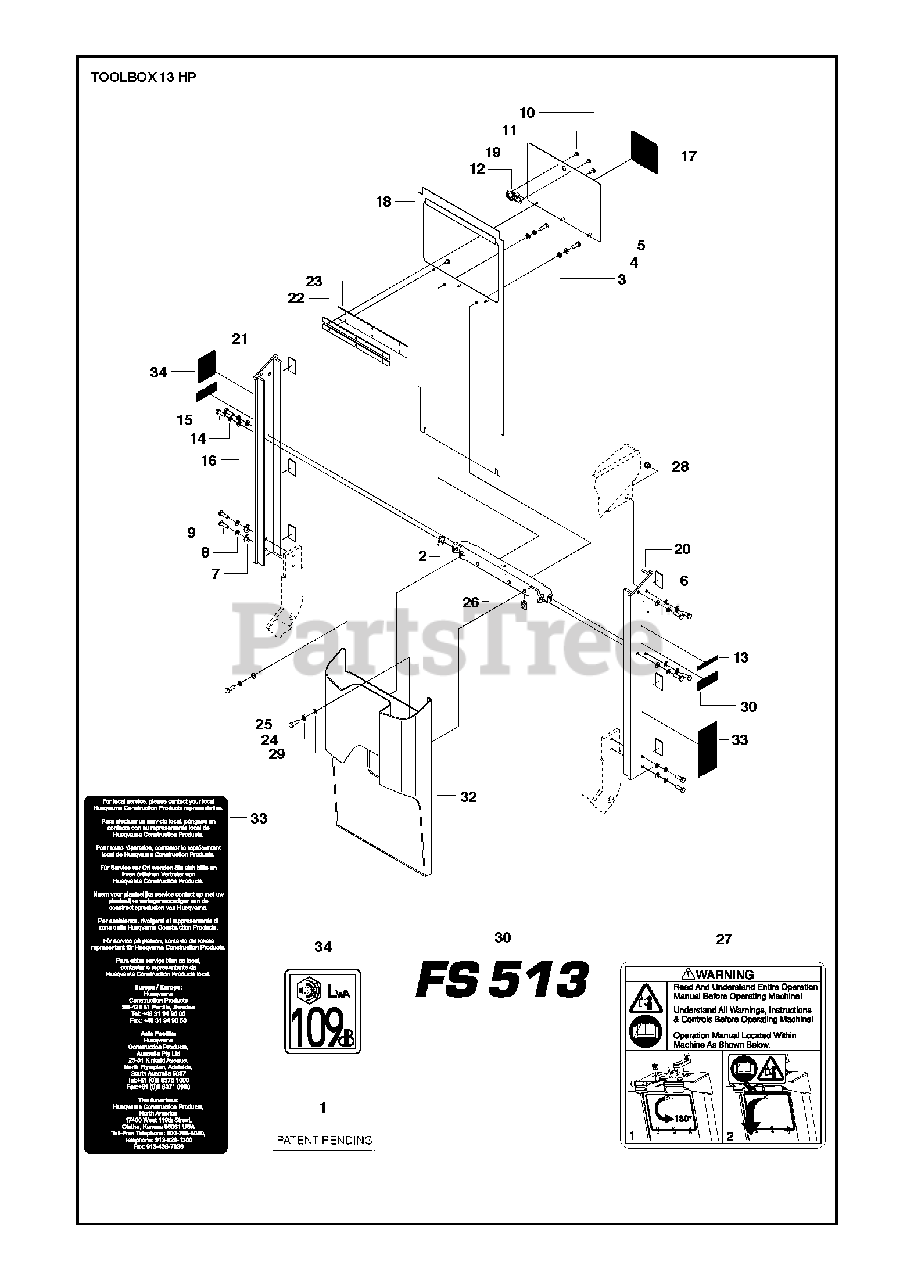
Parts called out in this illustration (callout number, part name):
3	WASHER
4	SPRING WASHER
7	WASHER
8	SPRING WASHER
14	SPRING WASHER
16	WASHER
24	SPRING WASHER
28	HEXAGON LOCKING NUT
29	WASHER
